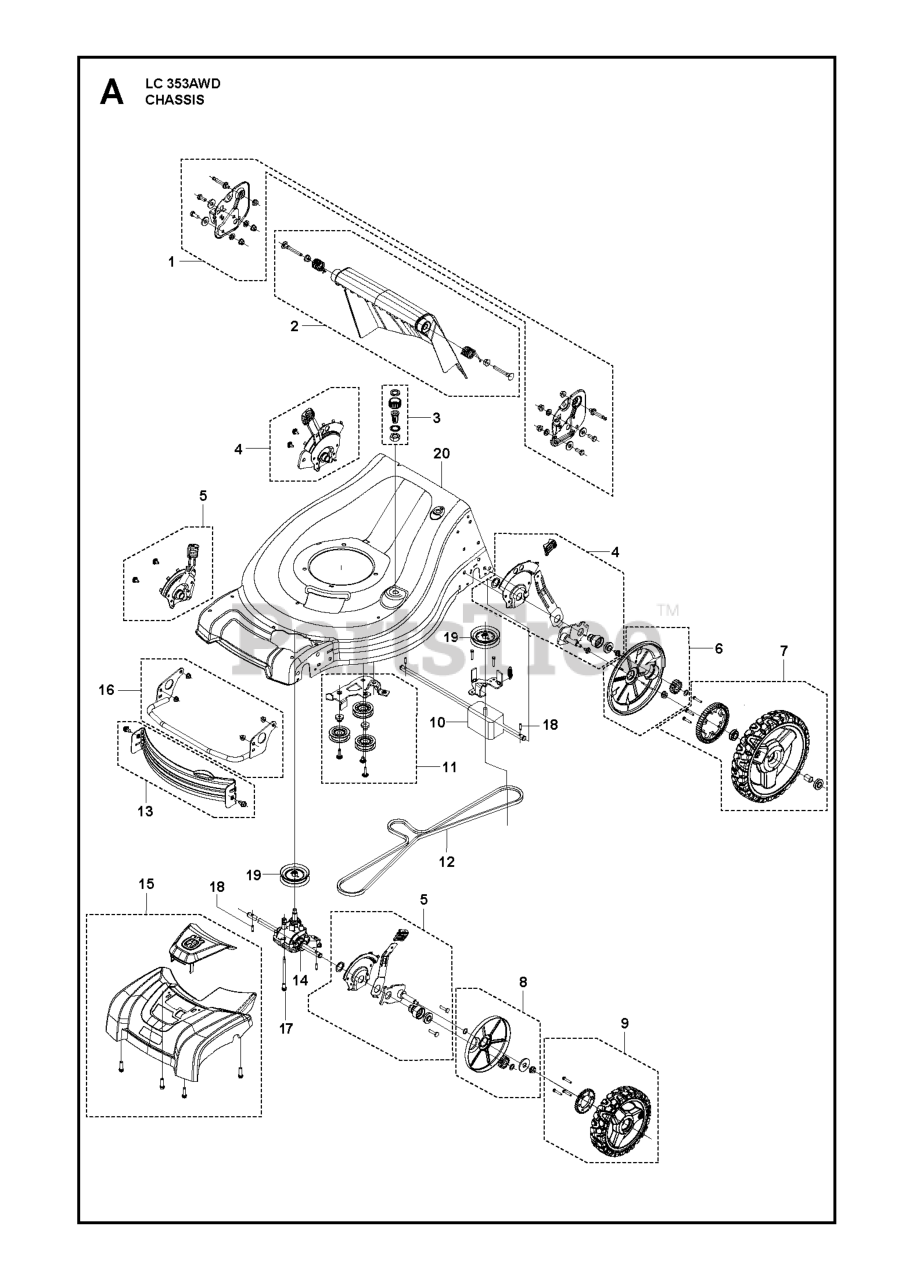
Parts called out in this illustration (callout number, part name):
3	KIT.WASH-OUT.PORT
9	Wheels
10	TRANSMISSION.AWD.REAR.21EFF
12	BELT.DRIVE.21EFF.AWD
14	TRANSMISSION.AWD.FRONT.21EFF
17	SCREW.HI-LO.5/16-14 X 4.10
18	PAWL, DRIVE
19	PULLEY AWD/RGD, SCREW-ON AWD/R
